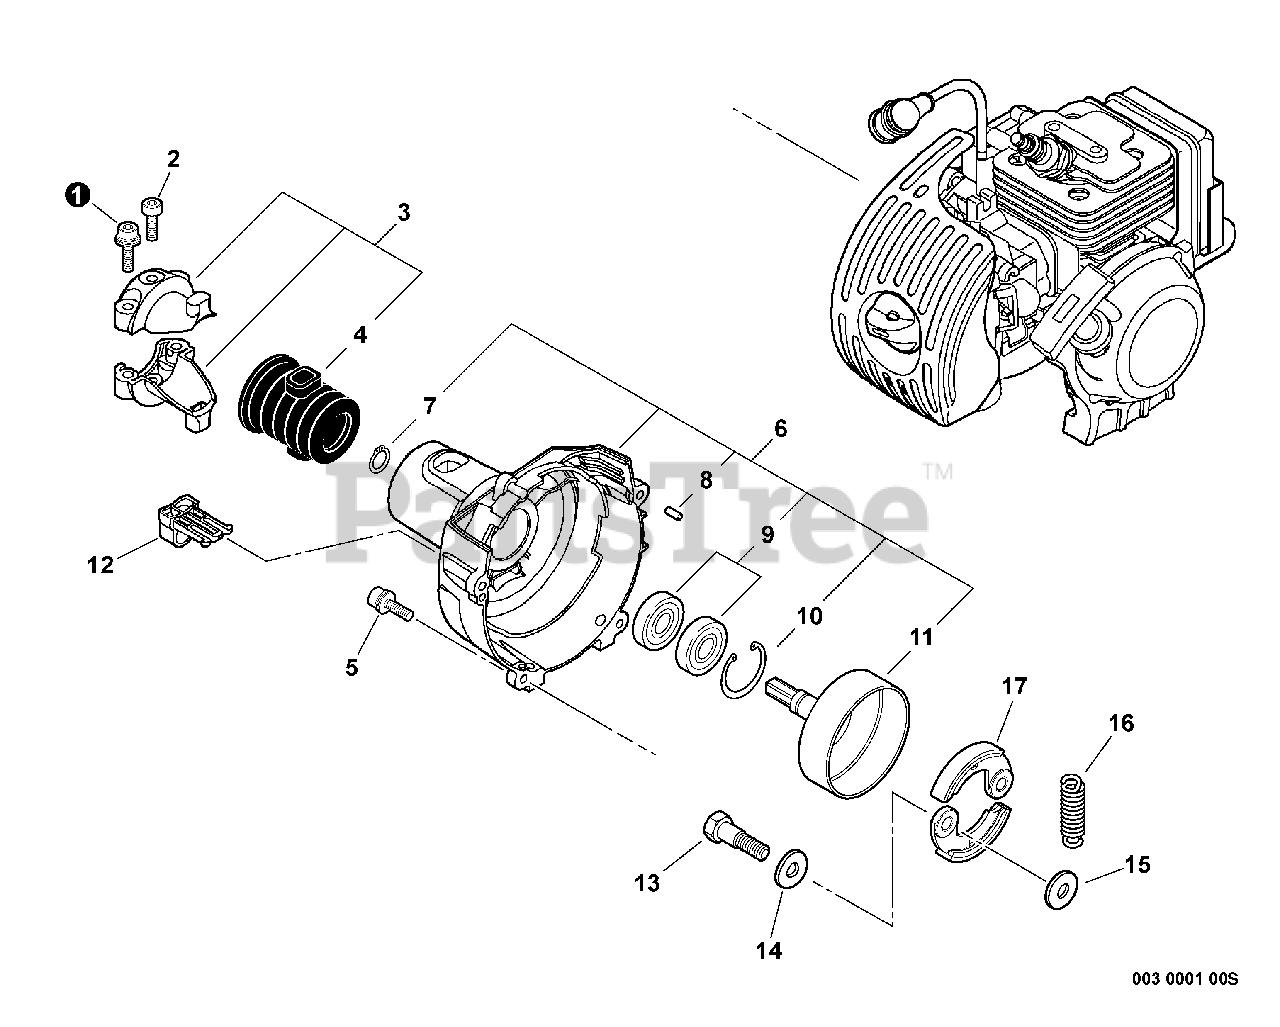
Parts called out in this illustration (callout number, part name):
1	BOLT 5×25
2	BOLT 5×12
3	HOLDER KIT, MAIN PIPE
4	CUSHION
5	BOLT 4×16
6	COVER ASSY, FAN
7	RING, RETAINING - 12
8	PIN, LOCATING 4
9	BEARING, BALL 6001
10	RING, SNAP 28
11	DRUM, CLUTCH
13	BOLT, CLUTCH 8×7.9×M6
14	WASHER, SPRING 8.5×16×0.5
15	WASHER 6.2×19×1.0
16	SPRING, CLUTCH
17	SHOE, CLUTCH
